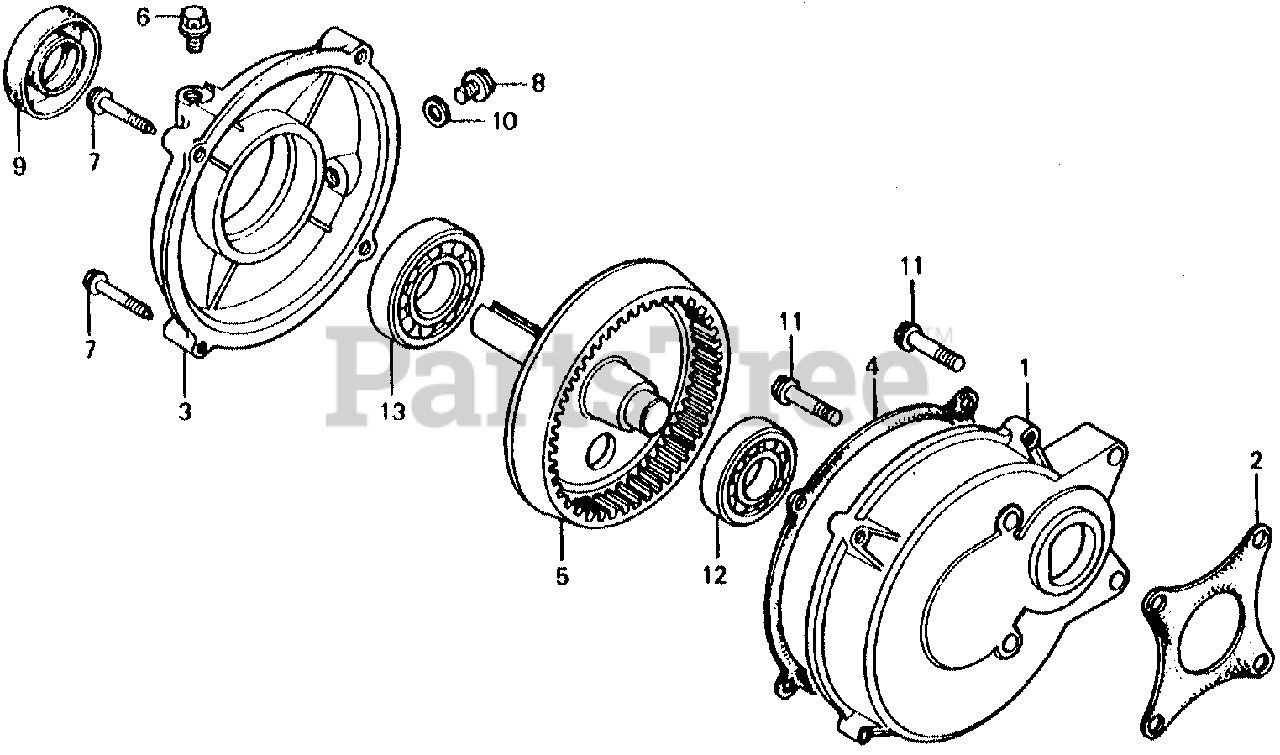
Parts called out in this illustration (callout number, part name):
1	CASE, REDUCTION
2	GASKET, REDUCTION CASE
3	COVER, REDUCTION
4	GASKET, REDUCTION COVER
5	SHAFT, P.T.O.
6	BOLT, BREATHING
7	BOLT, FLANGE (6X32)
7	BOLT, FLANGE (8X35)
8	BOLT, DRAIN PLUG
9	OIL SEAL (25X41X6)
10	WASHER, DRAIN PLUG (12MM)
11	BOLT, FLANGE (8X32)
12	BEARING, RADIAL BALL (6204)
13	BEARING, RADIAL BALL (6305)
